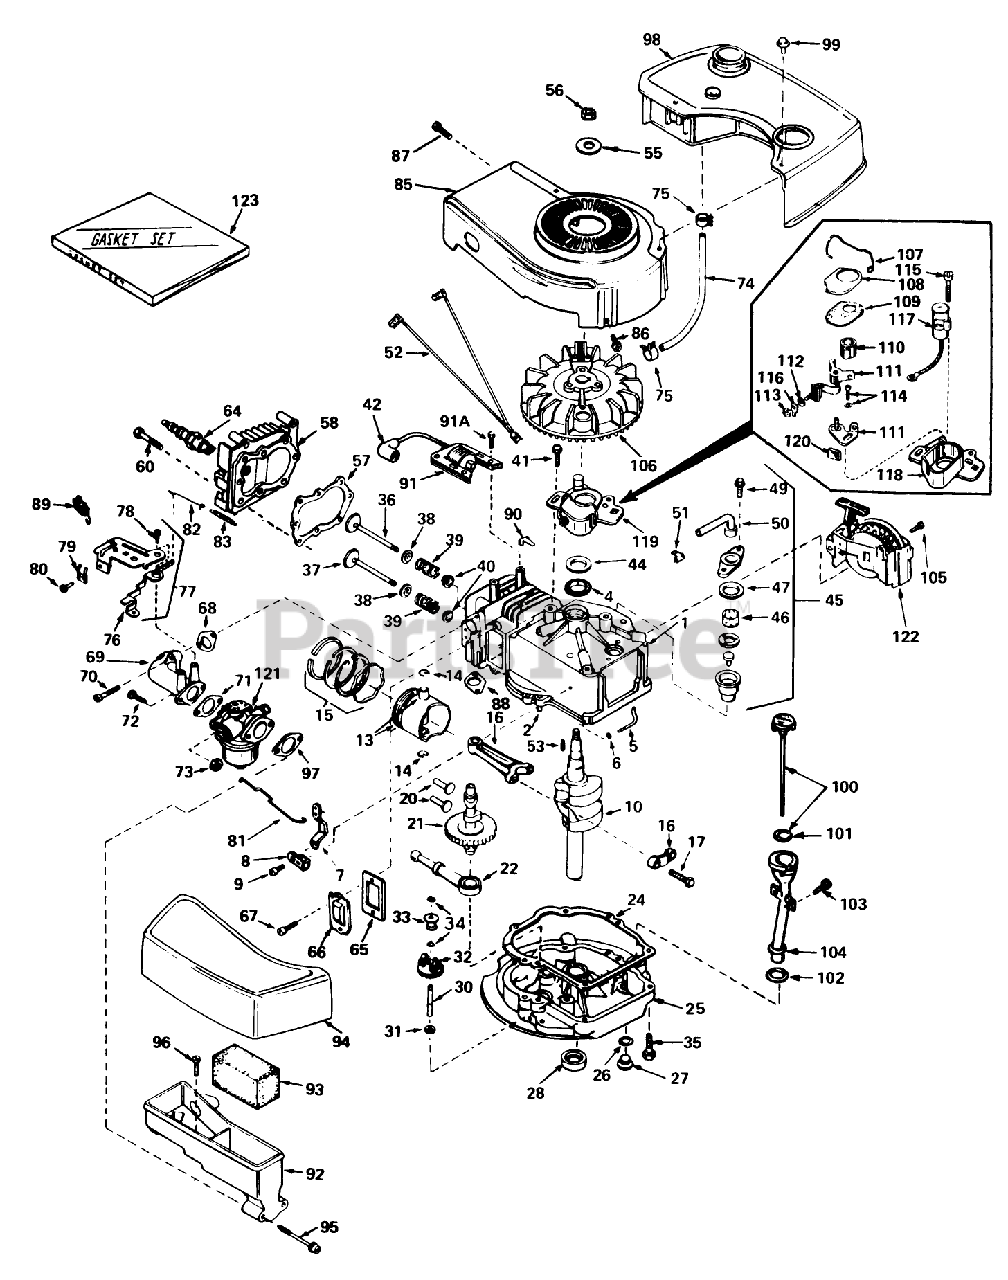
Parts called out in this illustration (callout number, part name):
1	Cyiinder Assy. (Incl. Ref. #2, 4 105)
2	Pin-Dowel
4	Seal-Oil
5	Rod, Governor (Incl. No. 36)
6	Washer-Flat
7	Governor Lever
8	Clamp-Lever, Governor
9	Screw
10	Crankshaft
13	Piston Pin Assy.(Incl. Ref. #14) (Std.)
13	Piston, Pin Ring Assy. (Std.)(Incl. Ref. #13A, 14 15)
13	Piston Pin Assy. (Incl. Ref. #14) (.010 Oversize)
13	Piston,Pin Ring Assy. (.010 over-size)(Incl. Ref. #13A, 14 15)
13	Piston Pin Assy. (.020 oversize) (Incl. Ref. #14)
13	Piston, Pin Ring Assy. (Incl. Nos. 13A, 14 15)(.020 oversize)
14	Ring-Retaining, Piston Pin
15	Ring Set Piston (Std.)
15	Ring Set Piston (.010 Oversize)
15	Ring Set Piston (.020 Oversize)
16	Rod Assy., Connecting (Incl. Ref. #17)
17	Bolt-Rod, Connecting
20	Lifter-Valve
21	Camshaft(Mech.Comp. Release)
22	Oil Pump ASM
24	Gasket, Mounting
25	Flange Assy., Mounting (Incl. Ref. #26thru 30)
26	Gasket-Oil Drain
27	Plug Oil Drain
28	Seal Oil
30	Shaft-Governor
31	Washer-Flat
32	Governor Gear ASM
33	Spool-Governor
34	Ring-Retaining
35	Screw (1/4-20 x 1-1/4)
36	Valve, Intake (Incl. Ref. #38, 39 40) (Std.)
36	Valve, Exhaust (1/32" Oversize) (Incl. Nos. 8, 9 10)
37	Valve, Exhaust (Standard) (Incl. Nos. 8, 9 10)
37	Valve, Exhaust (1/32" Oversize) (Incl. Nos. 8, 9 10)
38	Cap-Upper Valve Spring
39	Spring-Valve
40	Cap-Valve, Spring
41	Screw
42	Cover-Spark Plug
44	Gasket Stator
45	Breather Assy. (Incl. Ref. #46, 47, 49, 50 51 )
46	Element-Breather
47	Gasket-Breather
49	Screw, Hex Hd. w/Conical
50	Tube, Breaker
51	Clip, Breather
52	Wire Ground
53	682488 LB GRASS HI-
55	Washer-Belleville
56	Nut-Flywheel
57	63573 GIL 42 SNWTHW
58	Head-Cylinder
60	Screw (5/16-18x1-1/2)
64	Plug, Spark (J17LM or equiv.)
64	Plug, Spark (Champion RCJ-8)
65	Gasket-Breather
66	Cover-Valve
67	Screw
68	Gasket, Intake
69	Pipe, Intake
70	Screw (1/4-20 x 1)
71	Gasket-Carburetor
73	Nut and Lock Washer (1/4-28)
74	Line-Fuel
75	Clamp-Line, Fuel
76	Lever Control
77	Control Assy., Speed (Incl. Nos, 76, 78 89)
78	Screw, Hex Washer Hd Shoulder Self-Tap
79	Conduit
80	Screw (10-32 x 3/8)
81	Link-Throttle
82	Link Governor Spring
83	Spring Governor
85	Housing Blower
86	Screw
87	Screw (10-24 x 9/16)
88	Gasket Exhaust
89	Terminal
90	Clip-Wire
91	Lamination Coil Assy. (Incl. No. 42)
91A	Screw
92	Body Air Cleaner
93	Filer, Air
94	Cove, Air Cleaner
95	Screw Fil Hd.
96	Screw, Hex Hd.
97	Gasket-Air Cleaner
98	Tank, Fuel
99	Screw (10-32 x 35/64)
100	Dipstick, Oil (Incl. Ref. #101)(Twist Lock)
101	O-Ring
102	Gasket
103	Screw (10-32 x 1/2)
104	Tube-Oil Fill
105	Screw (1/2-20x5/8)
106	FIywheel
107	Spring Breaker Box
108	Cover-Dust
109	Gasket-Dust Cover
110	Cam-Breaker
111	Breaker Assy.
112	Washer
113	DECAL
114	Breaker Screw
115	Condenser Screw
116	Terminal, Ground
117	Condenser
118	Stator Plate
119	Stator Plate Assy. (incl. Nos. 107, 111 thru 118 120)
120	Felt,Cam Wiper
121	Carburetor (Incl. Ref. #71 )
122	Starter-Sidemount
123	53024/VAR.16HP O/P
